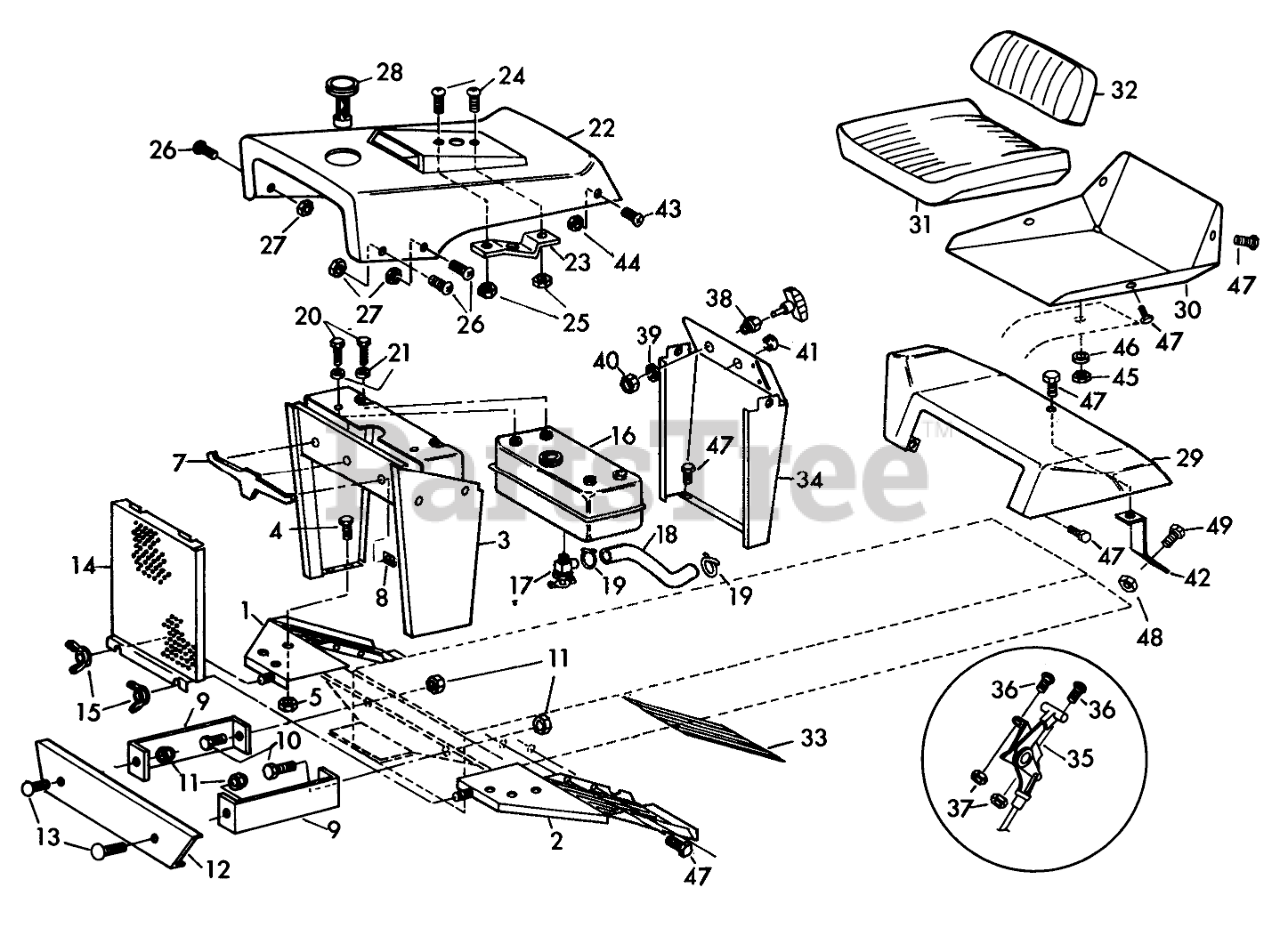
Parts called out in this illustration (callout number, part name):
1	Right Front Fender
2	Left Front Fender
3	Front Hood Support
4	SCREW-HH
5	Nut
6	SCREW-HH
7	Bullshead
8	Nut
9	Bracket
10	SCREW-HH
12	Bumper
13	BOLT-CARR
14	Grille
15	Wing Nut
16	Gas Tank
17	Shut Off Valve
18	Gas Hose
19	SCREW-HH
20	SCREW-HH
21	WASHER-LOCK
23	Bracket
24	Screw
25	Nut
28	Gas Gage
29	Rear Fender
30	Seat Frame
31	Bottom Seat Cushion
32	Back Cushion
33	Foot Pad
34	Rear Hood Support
35	Throttle Control
36	Screw
37	NUT-KEPS
38	Recoil Fitting
39	Washer
40	NUT-JAM
41	Plug Button
42	Fender Support Bracket
45	NUT-JAM
46	WASHER-LOCK
47	Screw
